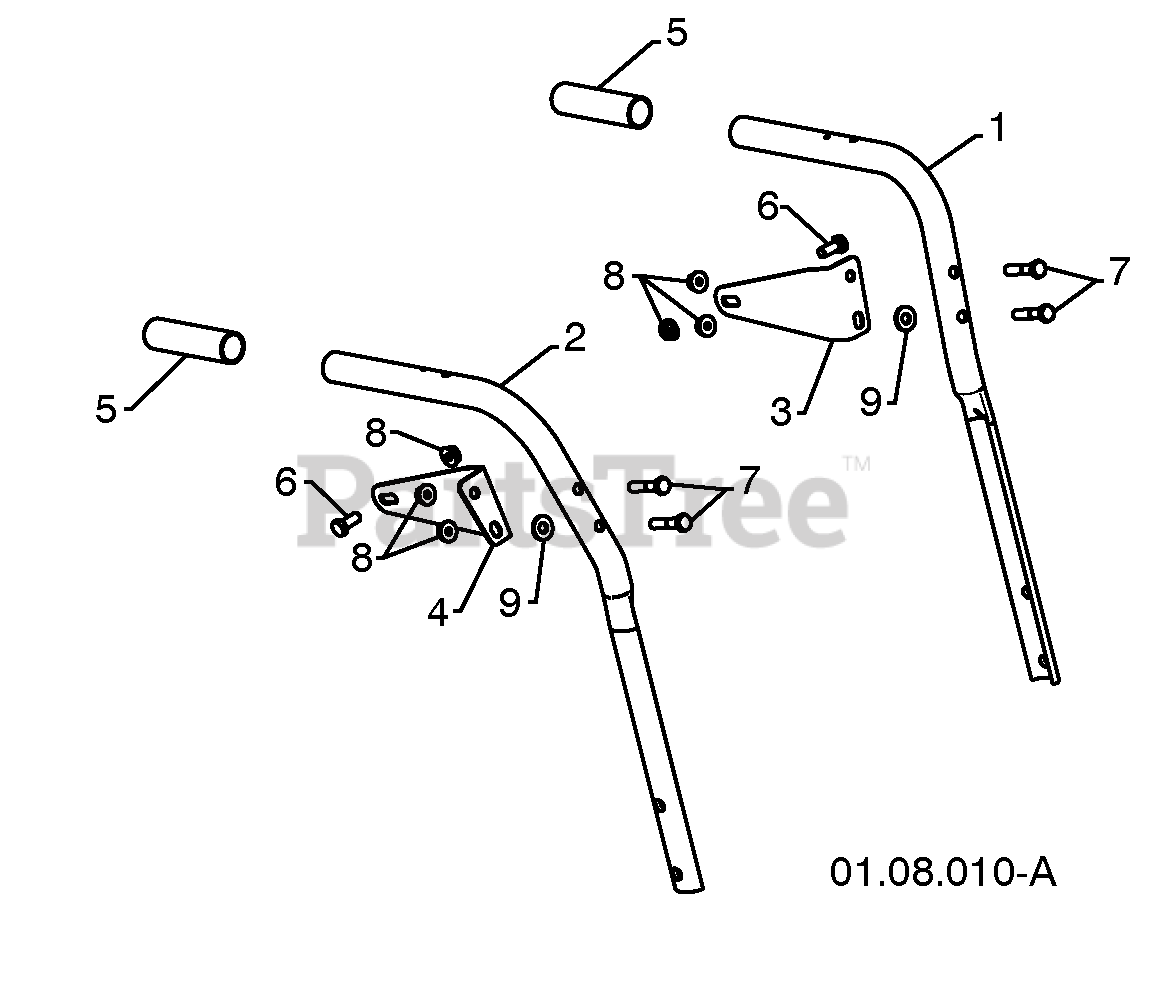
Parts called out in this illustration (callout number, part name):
1	PLOW HANDLE LH
2	PLOW HANDLE RH
3	PANEL BRACKET LH
4	PANEL BRACKET RH
5	HANDLE GRIP
6	SCREW 5/16-18 X .750
7	SCREW 5/16-18 X 1.50
8	NUT 5/16-18
